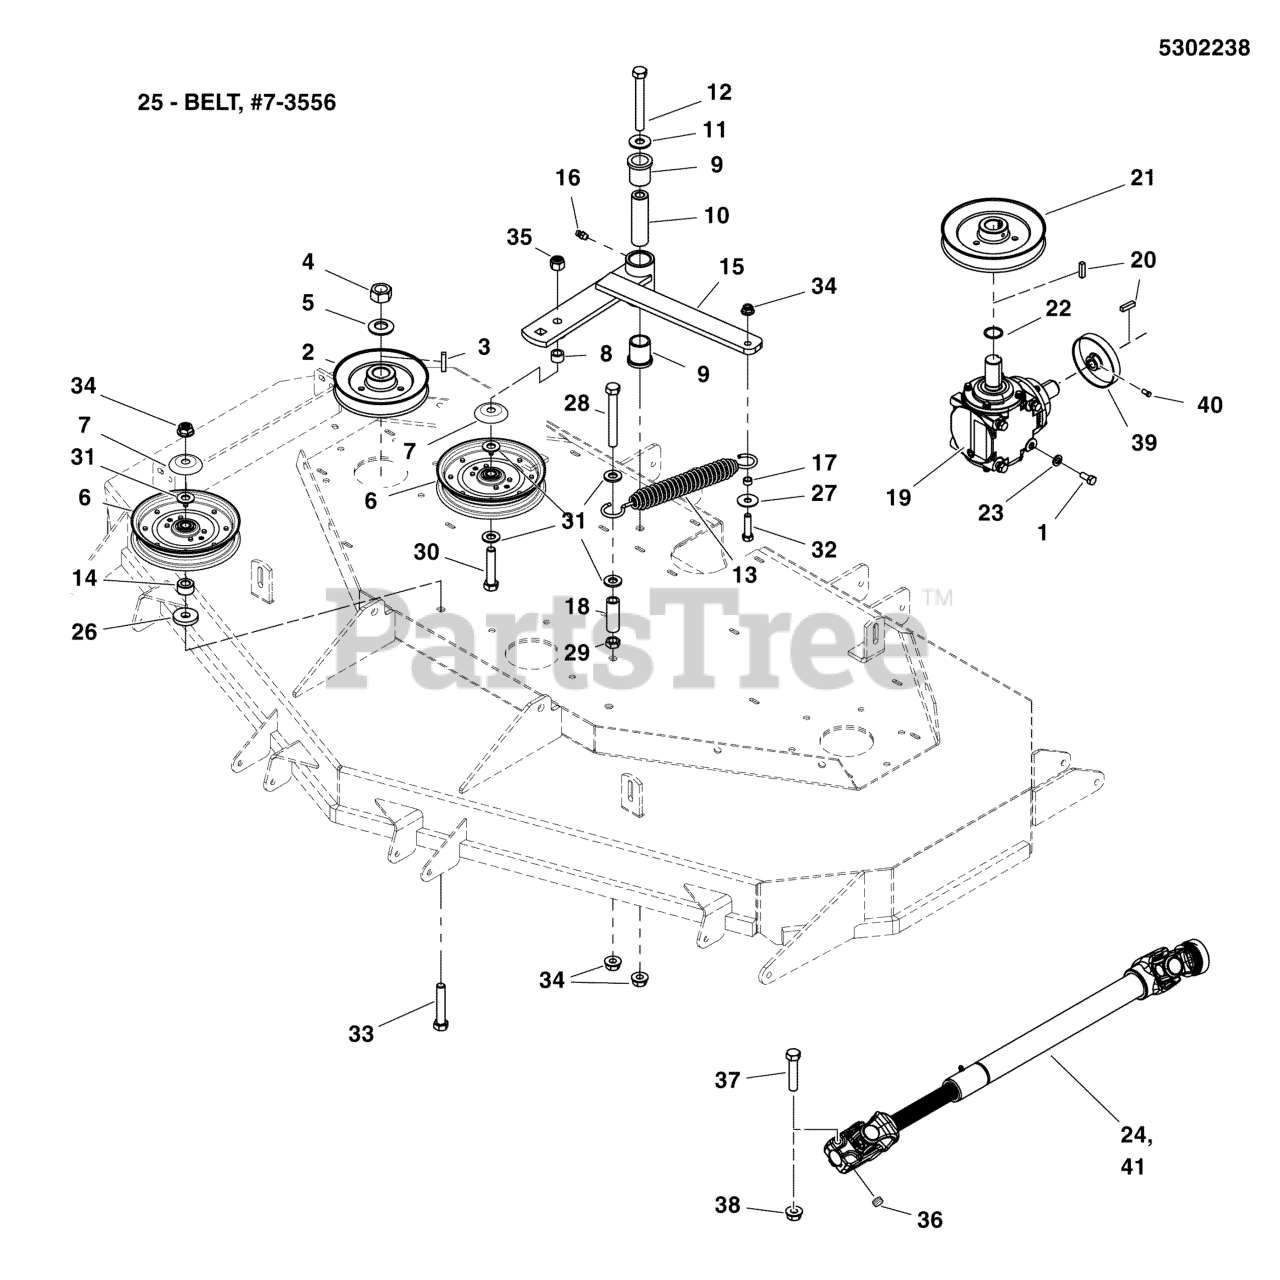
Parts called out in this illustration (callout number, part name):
1	BOLT, 5/16-18 X 3/4 GD5
2	PULLEY, 5.540OB X .985ID, SINGLE B-SEC
3	KEY, 1/4" SQ. X 1-1/4
4	WASHER, 3/4 BELLEVILLE CL/ZC
5	NUT, 3/4-16 Hex
7	SHIELD, PULLEY BEARING, CZ
8	SPACER, .52 X 1.00 X .63, YZ
9	BUSHING, FLANGE
10	SPACER, .52 x 1.00 x 3.50
11	WASHER, 1/2" USSZ
12	BOLT, 1/2-13 X 5" GD5 YZ
13	SPRING-EXT, 1.25 ODX5.70LGX.142WR, BLK
14	SPACER, .52 X 1.00 X .56, PM, CZ
15	WELD, IDLER ARM - OUTFRONT - RED
16	GREASE FITTING, 1/4-28 Straight
17	SPACER, .38 X .50 X .27, CZ
18	HOSE, 1/2" PUSH-ON 2.125"
19	GEAR BOX, RIGHT ANGLE
20	KEY, 1/4 SQ X 1
21	PULLEY, 6.25" SPLIT STEEL W/ 1" ID
22	SNAP RING, EXTERNAL, 1 SHAFT
23	WASHER, 5/16 LOCK CZ
24	DRIVE SHAFT, S800XY
25	BELT, BP-SEC, 130.97EL, LRG ARAMID, WRPD
26	WASHER, .53 X 1.50 X .25
27	WASHER, 3/8" Fender
28	BOLT, 1/2-13 X 4" GD5 CZ
29	NUT, Hex, Jam, 1/2-13
30	BOLT, 1/2-20 X 2-1/2" GD5 CZ
31	WASHER, 1/2 SAE
32	BOLT, 3/8-16 X 1-1/4" GD5 CZ
33	BOLT, 1/2-13 X 2-3/4 GD5 CZ
34	NUT, Hex Flange, Nylock, 1/2-13
35	NUT, Hex, Nylon Lock, 1/2-20
36	SET SCREW, 3/8-16 X 3/8
37	BOLT, 3/8-16 X 1-3/4" GD5 CZ
38	NUT, 3/8-16 HEX NYLON LOCK
39	GUARD, TRASH, S800X
40	SOC SET SCREW, 1/4-20X3/8, DRI-LOC PATCH
41	SHAFT, TELESCOPING DRIVE, OUT-FRONT
41	DRIVE SHAFT SEALED S800 GAS - NET
